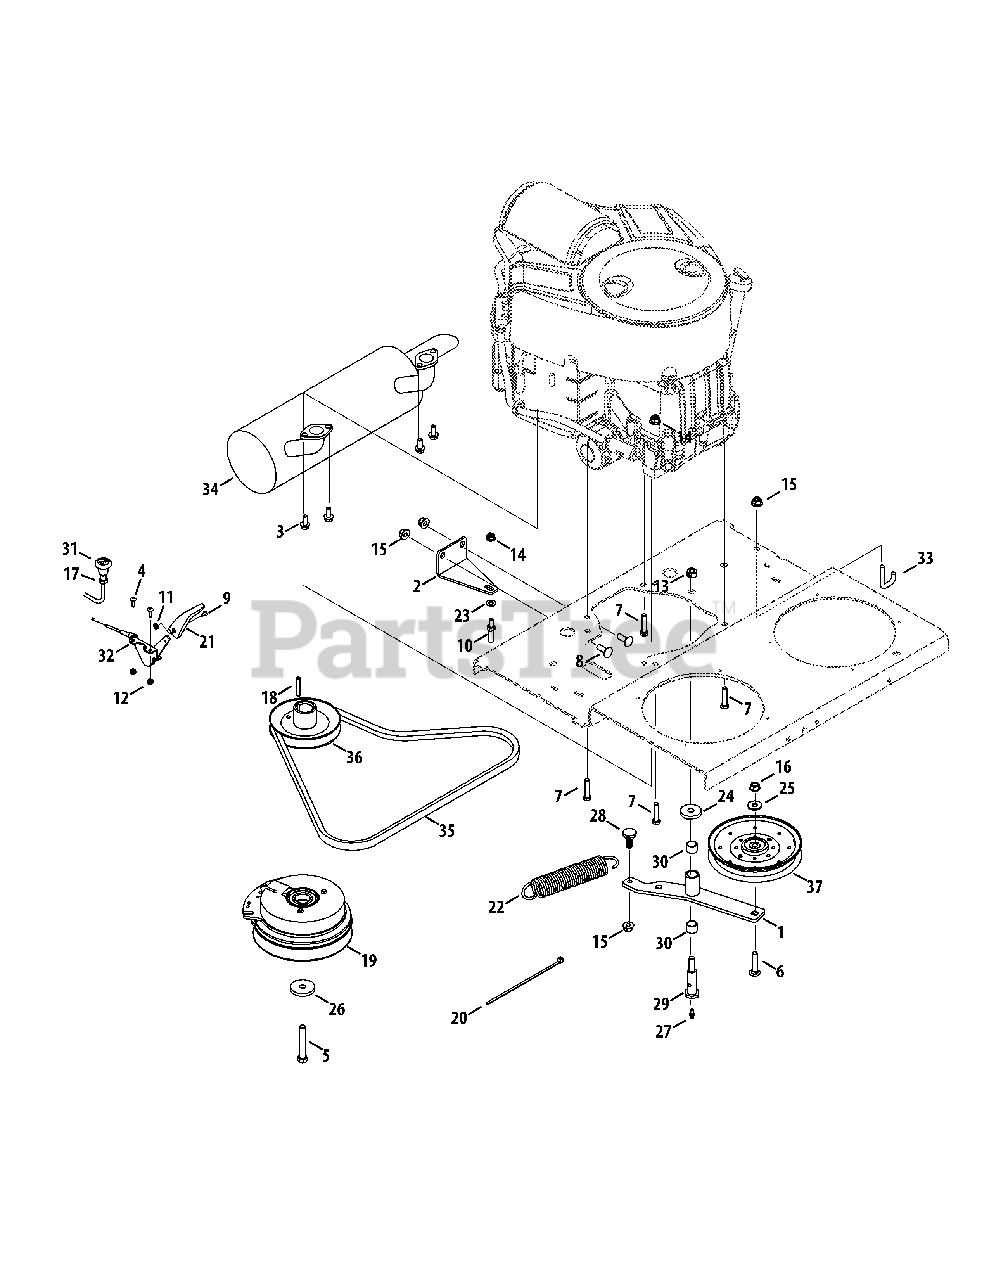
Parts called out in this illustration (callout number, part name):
1	Idler Bracket
2	Clutch Retainer Bracket
3	Hex Flange Screw, 5/16-18
4	Screw, #10-24 x .625
5	Hex Cap Screw, 7/16-20 x 2.75
6	Carriage Bolt, 3/8-16 x 1.00
7	Hex Cap Scrw, 5/16-18 x 1.50
8	Carriage Bolt, 3/8-16 x 1.00
9	Screw, #8-32 x .375
10	Stud, Pivot Ball Joint
11	Nut, #8-32, Hex
12	Nut, #10-24, Hexlock
13	Nut, 7/16-14, Hexlock
14	Nut, 5/16-18, Flangelock
15	Nut, 3/8-16, Flangelock
16	Nut, 3/8-16, Flangelock
17	Jam Nut, 3/8-24
18	Key, 1/4 x 1.50
19	Electric PTO Clutch
20	Cable Tie
21	Throttle Control Knob
22	Extension Spring, 1.5 x 7.5
23	Washer, .344 x .688 x .065
24	Washer, .471 x 1.50 x .225
25	Washer, .406 x 1.00 x .105
26	Washer, .471 x 1.50 x .225
27	Grease Fitting
28	Shoulder Screw, .625 x .302, 3/8-16
29	Shoulder Bolt, .625 x 1.947, 7/16-14
30	Bearing, .638 x .753 x .615
31	Choke Control Cable
32	Throttle Cable
33	Transmission Spring Hook
36	Drive Pulley
37	Idler Pulley
